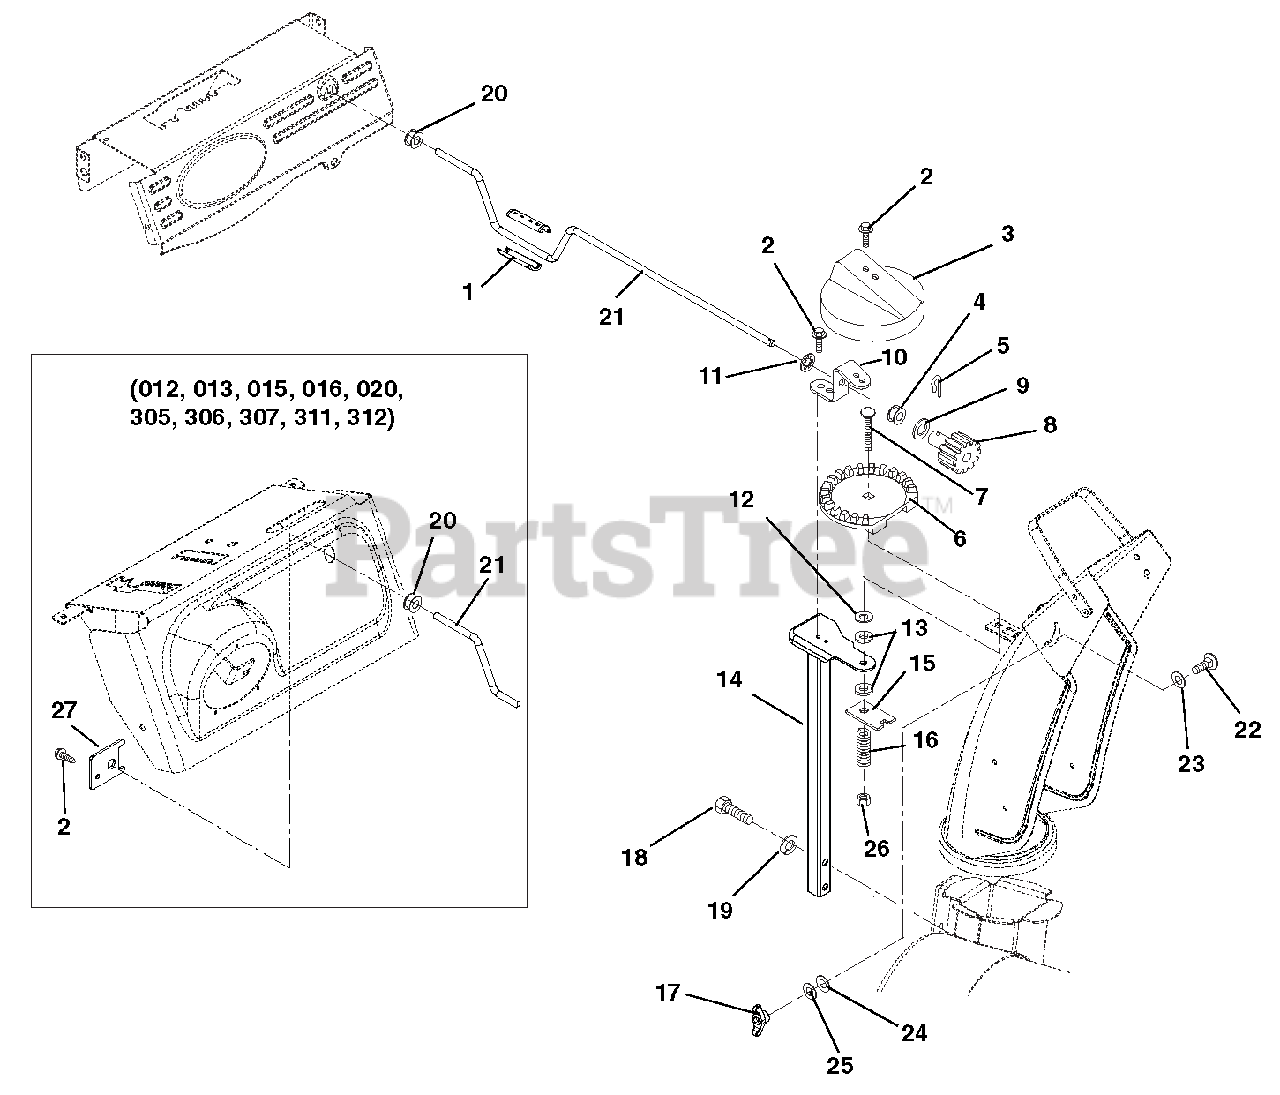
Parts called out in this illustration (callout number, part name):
1	KNOB, CRANK-SNAP
2	SCR-TAP .25-20X.50 HWH TR YWZ
3	GEAR COVER
4	BUSHING, POLYLINER-.63 SNAPIN
5	PIN, SPRING CLIP
6	CHUTE GEAR
7	@BLT-RDHDSQNK .38-16X2.50 G5YZ
8	PINION GEAR W/BRACKET
9	WSHR-THRST .625 X 1.0 X .03
10	BRACKET, PINION GEAR
11	PUSHNUT .625
12	WSHR-FL-STL .380X1.50X.062 YWZ
13	FRICTION WASHER
14	PEDESTAL, CHUTE - CRANK
15	PLATE, FRICTION
16	SG-COMP .187X.56X1.62
17	KNOB,WING .38-16 UNC NYL/TALC
18	@BLT-HEX .38-16X1.75 GR5 YWZC
19	@WSHR-LK .38X.094 REG YWZC
20	BUSHING, POLYLINER-.38 SNAPIN
21	ROD, CHUTE CRANK
22	@BLT-RDHDSHSQNK.38-16X1.0 G5YZ
23	WSHR-FL-STL .52X.827X.062 YWZC
24	WSHR-FL-NY .375X.75X.060
25	@WSHR-FL-STL.406X.812X.065 YWZ
26	@NUT-LK-TOP-FLG .38-16 YWZC
27	BRACKET, CHUTE CRANK
